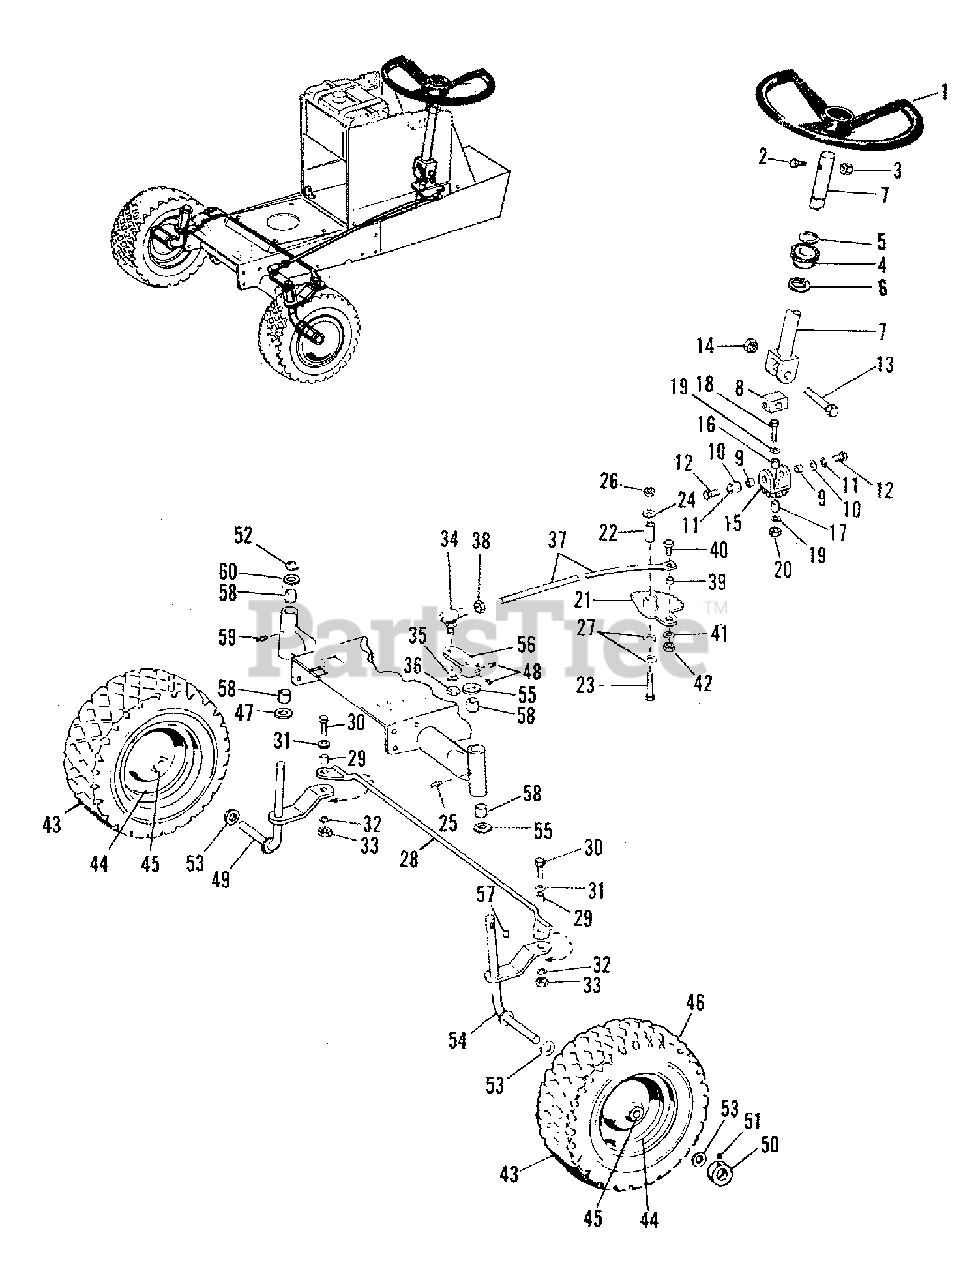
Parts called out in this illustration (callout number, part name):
1	WHEEL ASSEMBLY, Steering
2	CAPSCREW, Hex, 5/16-18 x 1-1/4" Large
3	LOCKNUT, Full, Hex, 5/16-18
4	BUSHING, Steering
5	WASHER, (As Required)
6	RING, Snap
7	SHAFT ASSEMBLY, Steering
8	PIN, Universal Joint
10	WASHER, Plain, 3/8"
11	LOCKWASHER, 3/8"
12	CAPSCRE, Hex, 3/8"-16 3/4" Large
13	CAPSCREW, Hex, 3/8"-16 x 3/4" Large
14	LOCKNUT, Full, Hex, 5/16-18
15	FORK & PINION ASSEMBLY
18	CAPSCREW, Hex, 3/8"-16 X 1-1/2" Large
20	LOCKNUT, Hex, Jam, 3/8"-16
21	GEAR ASSEMBLY, Steering
23	CAPSCREW, Hex, 3/8"-16 X 2-1/2" Large
24	WASHER, Plain, 3/8"
25	FITTING, Grease
26	LOCKNUT, Full, Hex, 3/8"-16
27	WASHER, Special
28	LINK ASSEMBLY, Drag
30	SCREW, Special
31	WASHER, Plain, 3/8"
32	LOCKWASHER, 3/8"
33	NUT, Full, Hex, 3/8"-16
34	JOINT, Ball
35	LOCKWASHER, 1/2"
36	NUT, Full, Hex, 1/2"-20
38	NUT, Hex, Jam, 1/2-20"
40	CAPSCREW, Hex, 3/8"-16 x 1" Large
41	WASHER, Plain, 3/8"
42	LOCKNUT, Full, Hex, 3/8"-16
43	WHEEL & TIRE ASSEMBLY
48	SETSCREW, 5/16"-18 x 1/2" Large
49	SPINDLE ASSEMBLY, R.H.
50	COLLAR, Set
51	SETSCREW, 5/16"-18 x 5/16" Large
52	RING, Retaining
54	SPINDLE ASSEMBLY, L.H.
56	LEVER ASSEMBLY, Steering
